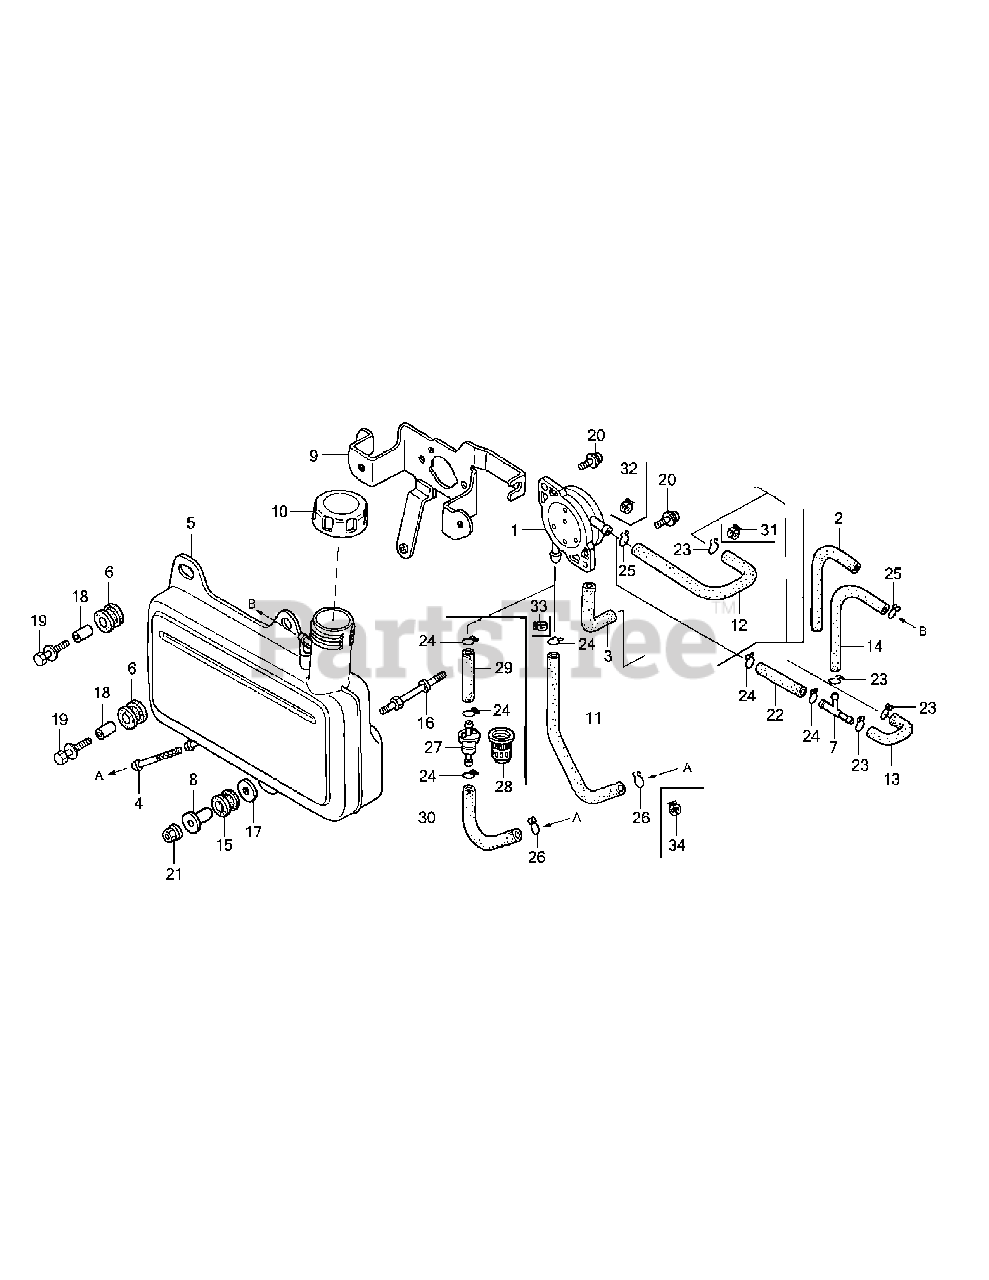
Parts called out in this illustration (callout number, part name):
1	Fuel Pump Assembly
2	Supporter Rubber, 107mm
3	Diaphragm Tube
6	Tank Mounting Rubber B
7	Fuel Tube Joint
8	Fuel Tank Setting Collar
9	Fuel Tank Stay A
10	Fuel Tank Cap Assembly
14	Fuel Return Tube
15	RR. Fender Rubber
16	Stud Bolt, F/Tank
17	Washer, 8MM
18	Collar, 14 x 6.1
19	Bolt-Washer, 6 x 25
20	Screw-Washer, 5 x 14
21	Flange Nut, 6mm
22	Fuel Bulk Hose, 5.5 x 300/5.5 x 33
23	Tube Clip, B8
24	Tube Clip, B10
25	Tube Clip, C9
26	Tube Clip, C11
27	Fuel Filter
28	Strainer Suspension
29	Fuel Pump Tube
30	Fuel Tank Tube
